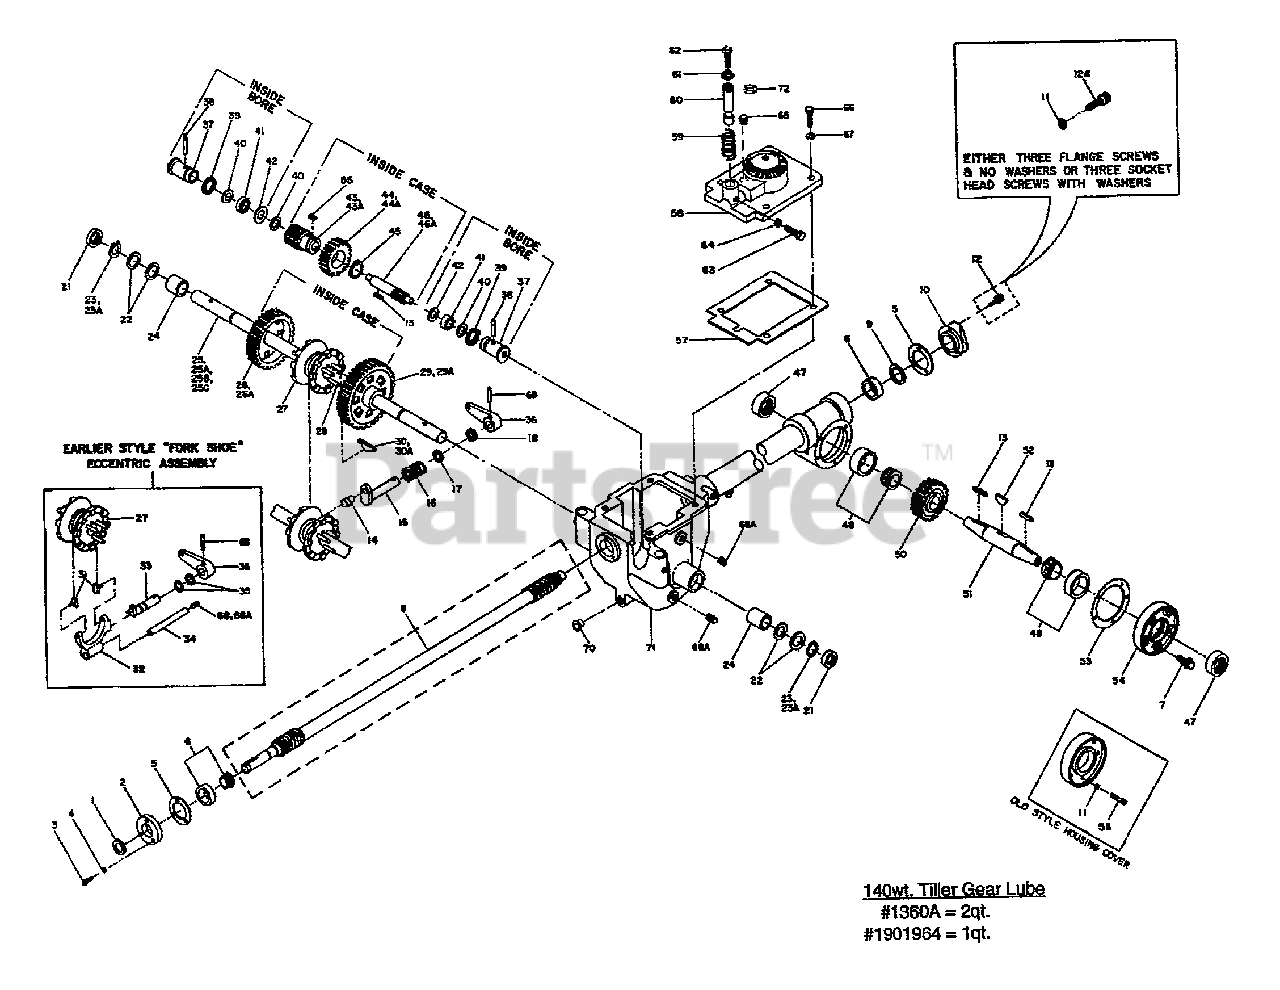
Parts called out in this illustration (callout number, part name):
1	SEAL-PINION SHAFT PT/85030/00
2	COVER-FRONT
3	SCR-HH 1/4-20X.75 G5 ZP
4	WASHER-LK .25 ZP
5	GASKET-BRG COVER
6	KIT-BRG CONE&RACE-DRIVESHAFT
7	SCR-HH 1/4-20X.625
8	KIT-DRIVESHAFT HORSE
9	SHIM-1.75X1.5X.01
9	SHIM-1.75X1.5X.03
9	SHIM-1.75X1.5X.005
10	CAP-REAR #1115
11	WASHER-LK .25 HI-COLLAR
12	SCR-HFLK 1/4-20X.875
12A	SCR-HXSKT 1/4-20X1.0
13	KEY-.188 SQX1.0
14	PIN-.375 X .72
15	SHAFT-ECCENTRIC HORSE TLR
16	SPRING .845 X 1.25
17	WASHER # .875 X .65 X .06
18	SEAL-OIL ECCENTRIC
21	SEAL-OIL WHEELSHAFT
22	SHIM-1.375X1.015X.062
22	SHIM-1.375X1.015X.03
22	SHIM-1.375X1.015X.015
22	SHIM-1.375X1.015X.01
22	SHIM-1.375X1.015X.005
23	RING-HEAVY EXT .906 ID
23A	RING-RETAINING 5100-100
24	BUSHING-1.25X1.005X1.5
25	KIT-WHEELSHAFT
25A	KIT-WHEELSHAFT
25B	KIT-WHEELSHAFT
25C	KIT-WHEELSHAFT
26	GEAR-SPUR 46 TEETH MACH
26A	GEAR-SPUR-50 TEETH-MACH
27	CLUTCH-MACH
28	PIN-CLUTCH .25 2.65
29	GEAR-SPUR 56 TEETH MACH
29A	GEAR-SPUR 60 TEETH-MACH
30	KEY-HI PRO .25X1.812
30A	KEY-HI PRO .25X1.062
31	PIN-.375 X .72
32	CLUTCH FORK
33	SHAFT-ECC WITH O RING
34	PIN-.5X4.0 FORK #
35	RING-O .625 X .438
36	LEVER-ECC. #1029
37	PLUG-PINION BRG W/RING
38	PIN-SPIROL .25 X 2.0
39	RING-O 1 ID
40	SHIM-1.234X1.015X.033
40	SHIM-1.234X1.015X.062
40	SHIM-1.234X1.015X.01
41	BRG-BALL (7 BALLS)
42	WASHER-# 1X.484X.06
43	GEAR-SPUR 20 TEETH MACH
43A	GEAR-SPLINE-16 TEETH-MACH
44	GEAR-WORM 36 TEETH MACH
44A	GEAR-WORM-30 TEETH-MACH
45	RING-RETAINING 5100-150
46	GEAR-SPLINE 10 TEETH MACH
46A	GEAR-SPLINE 6 TEETH MACHINE
47	SEAL-OIL TILLERSHAFT
48	TAPERED, BEARING & CUP
50	WORM GEAR
51	SHAFT-TILLER W/KEY
52	KEY-WOODRUFF .25X1.12
53	GASKET-TILLER COVER
54	COVER-W/SCRS(TLR) (9780)
55	KEY
56	SCR-HXSKT 1/4-20X.625
57	GASKET-TRANS COVER
58	ASSM-COVER W/BOLT-HORSE
59	SPRING .78 X 2.125
60	ASSM-NEUTRAL PLUNGER
61	NUT-HFLK 3/8-16 ZP
62	BOLT-HH 3/8-16X1.5 FTH ZP
63	SCR-HH 5/16-18X1.0 G5 ZP
64	NUT-HEX 5/16-18 ZP
65	PLUG-PIPE 3/8 NPT
66	BOLT-HH 3/8-16X1.5 FTH ZP
68	PLUG-PIPE 3/8 NPT
68A	PLUG-PIPE 1/4 NPT
70	PLUG-CAP (RED)
71	TRANSMISSION CASE, HOUSING & TUBE ASSEMBLY
72	RING-KLIP EXT .594 ID ZP
